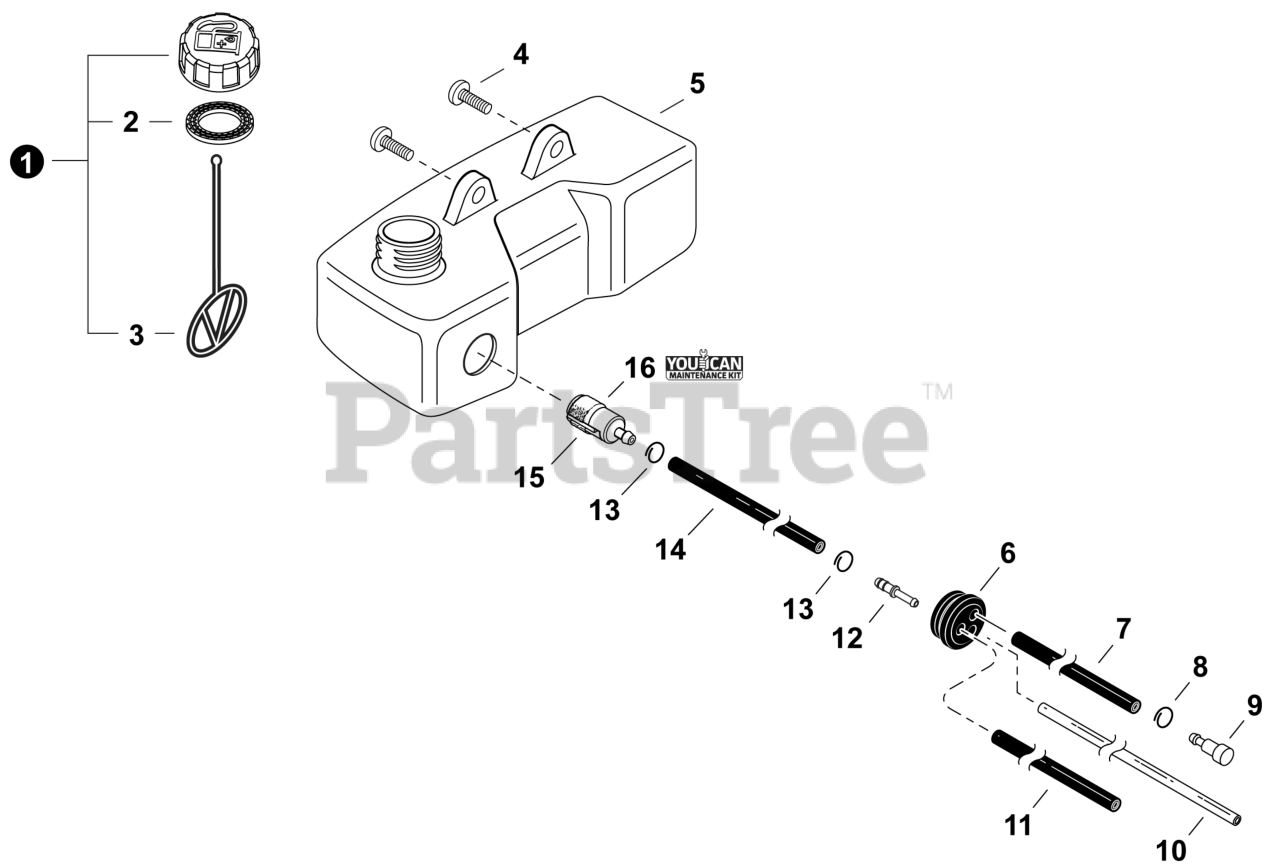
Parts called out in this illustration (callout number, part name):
1	CAP ASSY, FUEL
2	GASKET, FUEL CAP
3	CONNECTOR, CAP L= 100 MM
4	SCREW 5x15
5	TANK ASSY, FUEL
6	GROMMET, FUEL 5
7	PIPE, FUEL 3x5x70 BLACK
8	CLIP 5.5
9	VENT ASSY
10	PIPE, FUEL 3x6x50 YELLOW
11	PIPE, FUEL 3x5.5x70 BLACK
12	CONNECTOR, PIPE 5x3.5
14	PIPE, FUEL 3x5x140 BLACK
15	FILTER, FUEL
16	TUNE-UP KIT - YOUCANT
